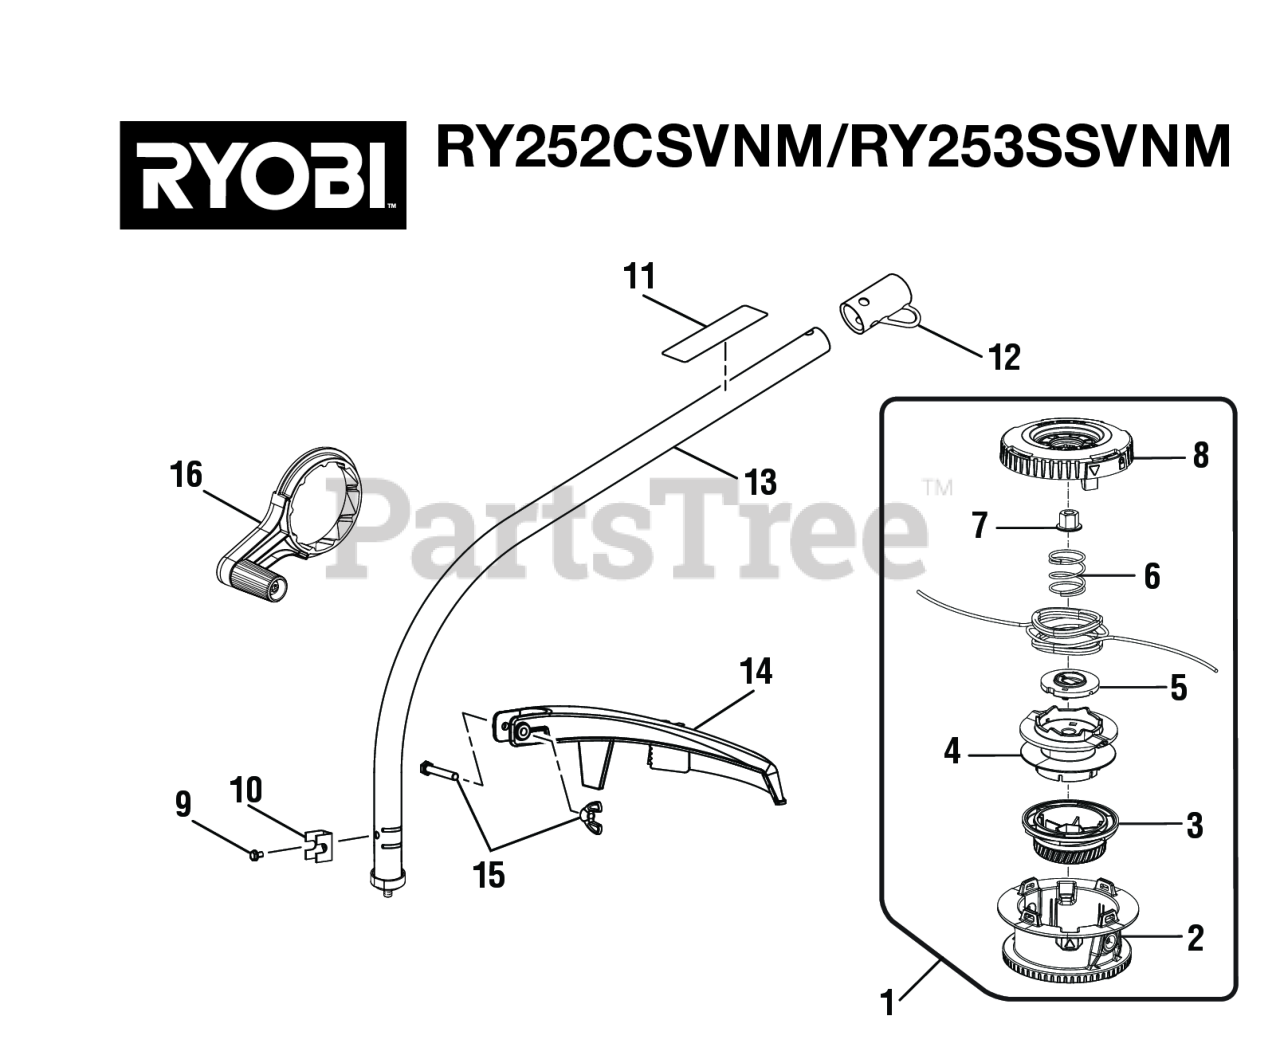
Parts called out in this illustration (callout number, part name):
1	Trimmer Head Assembly (.095) (Inc. Key Nos. 2-8)
2	Bump Head
3	Bump Knob (Green)
4	Spool Assembly
5	String Guide
6	Compression Spring
7	Flange Nut (M8)
8	Locking Assembly
9	Screw (#10-32 x 3/8 in., Hex Washer Hd. S.T.)
11	Warning Icon Label
12	Hanger Cap
13	Curved Shaft Assembly (Inc. Key Nos. 9-12)
14	Grass Deflector Assembly
15	Fastener Parts Kit
16	Crank Handle
